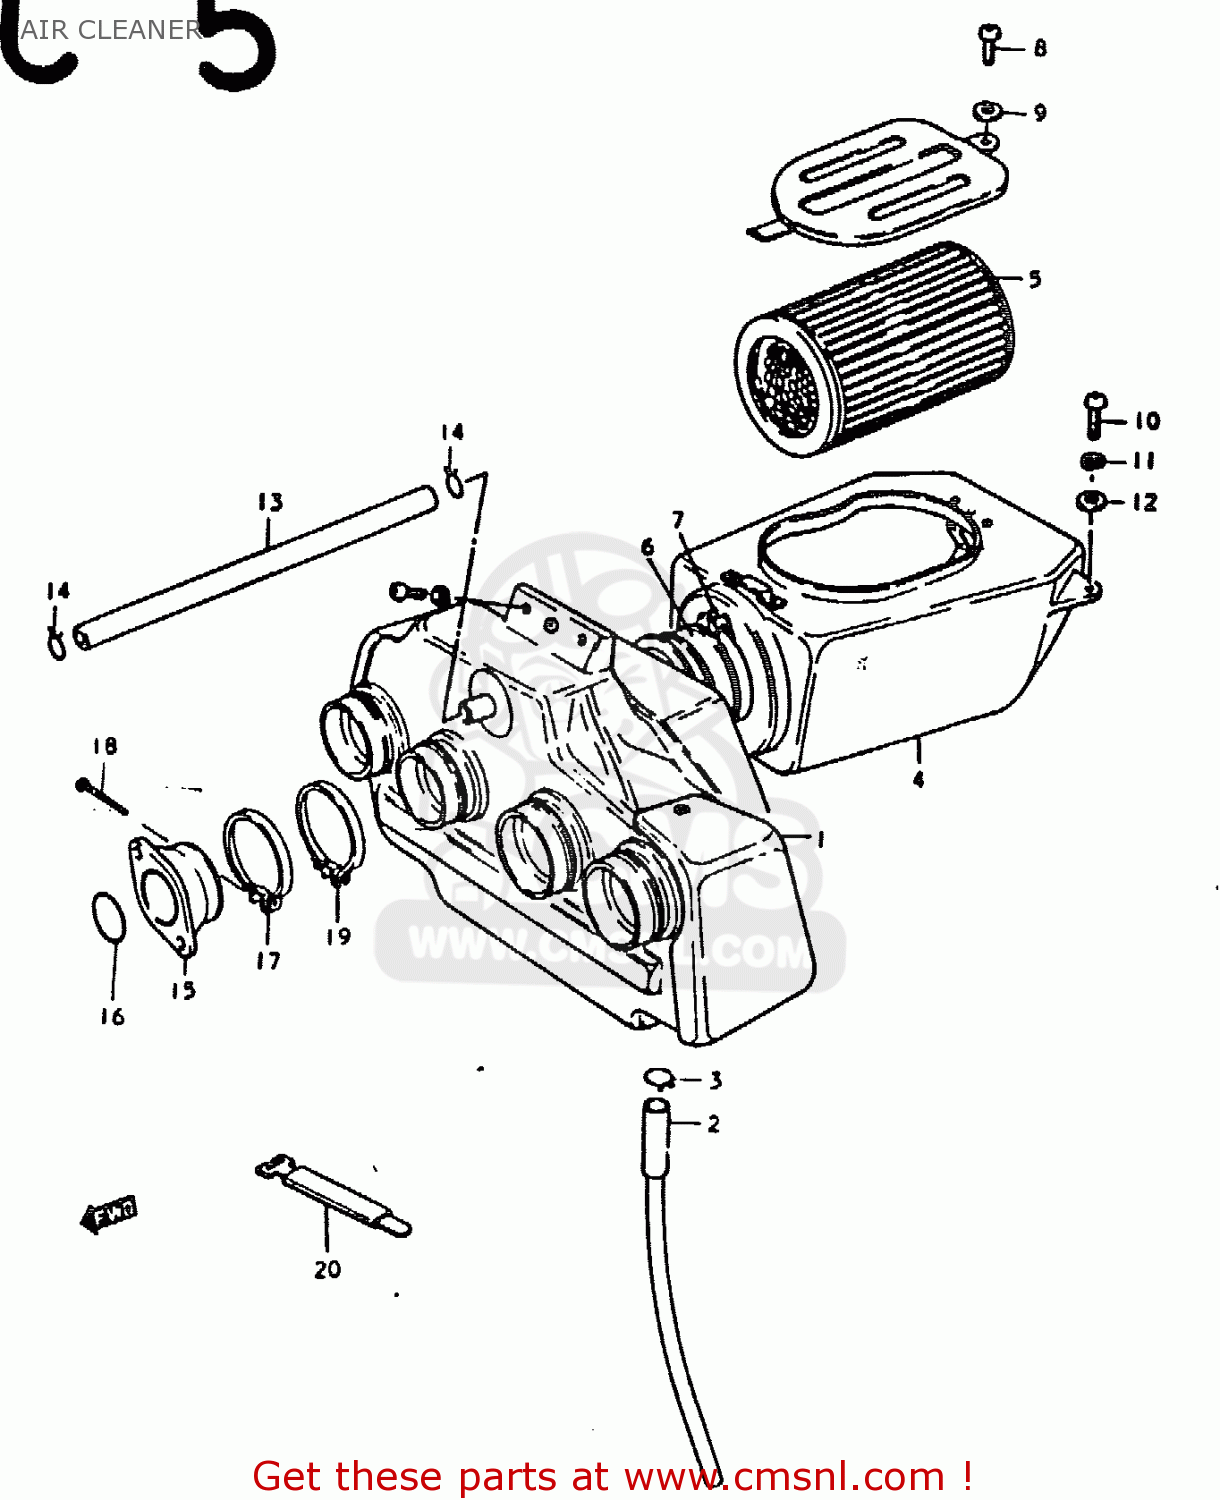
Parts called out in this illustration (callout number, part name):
1	CASE COMP,AIR CLEANER
2	HOLDER,FILTER
3	HOSE,AIR CLEANER
4	CASE ASSEMBLY,AIR CLEANER
5	FILTER,AIR CLEANER
6	HOSE,AIR CLEANER
7	BAND
8	SCREW
9	WASHER
10	BOLT, UPPER
11	LOCK WASHER
12	WASHER
13	HOSE
14	CLIP
15	PIPE,INTAKE
16	O RING(D:2.4,ID:31.7)
17	CLAMP
18	SCREW
19	CLAMP
20	CLAMP(L:120)
